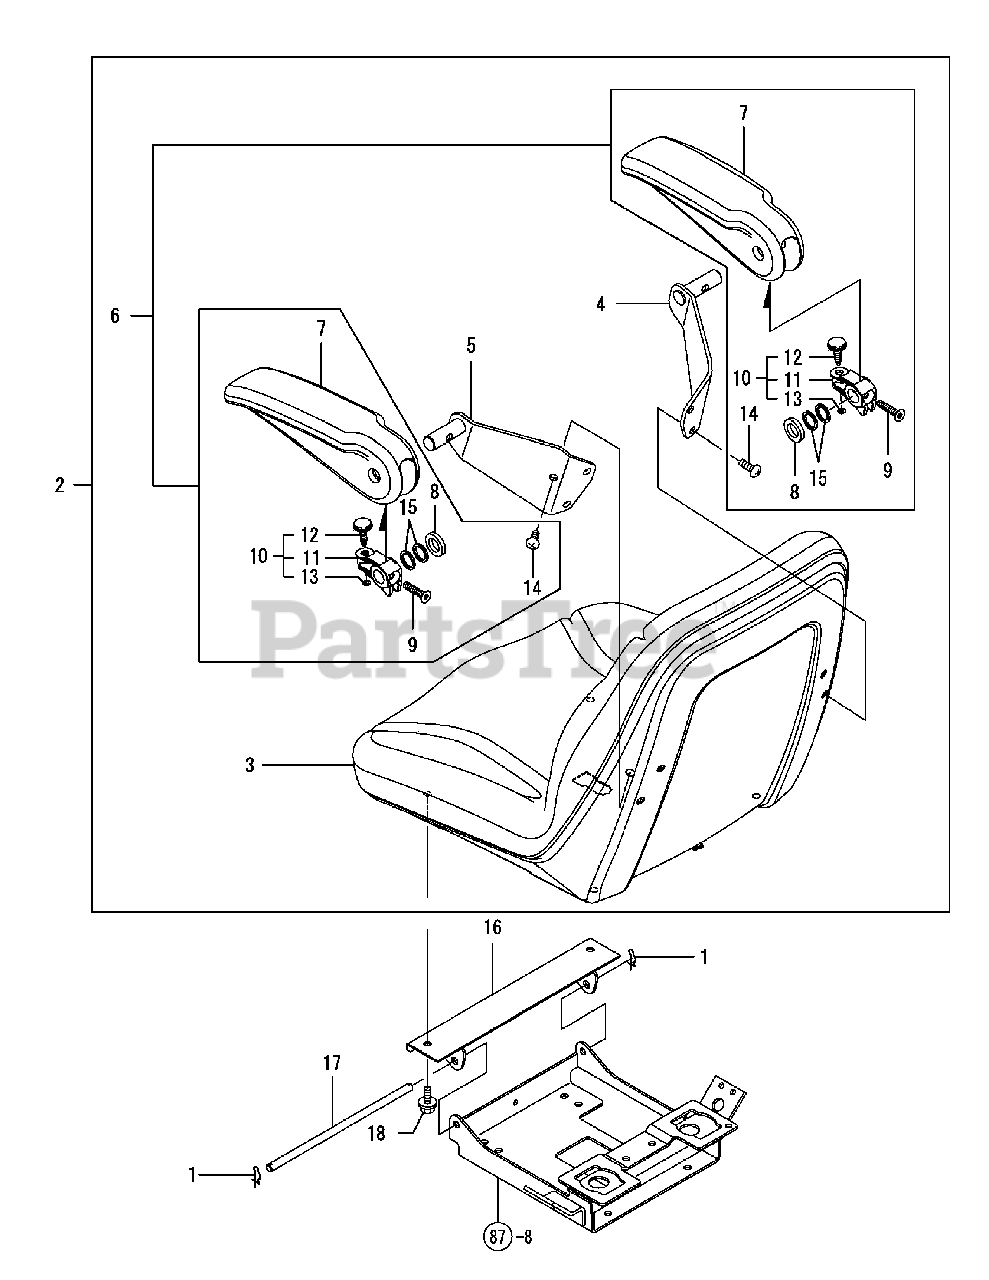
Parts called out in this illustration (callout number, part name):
1	Pin 8,Come-Off Snap
3	Seat Assy, Operator
4	Bracket Assy, R.H.
5	Bracket Assy, L.H
6	Replace Kit, Armrest
8	Spacer,
9	Screw, 5/16-18 Unc
10	Stop Assy, Armrest
11	Stop, Armrest
12	Knob, Adjust
13	Ring, Retainer
14	Screw, 5/16-18
15	Spacer,
16	Hinge Assy, Seat
18	Bolt M 8X 16 Plated
